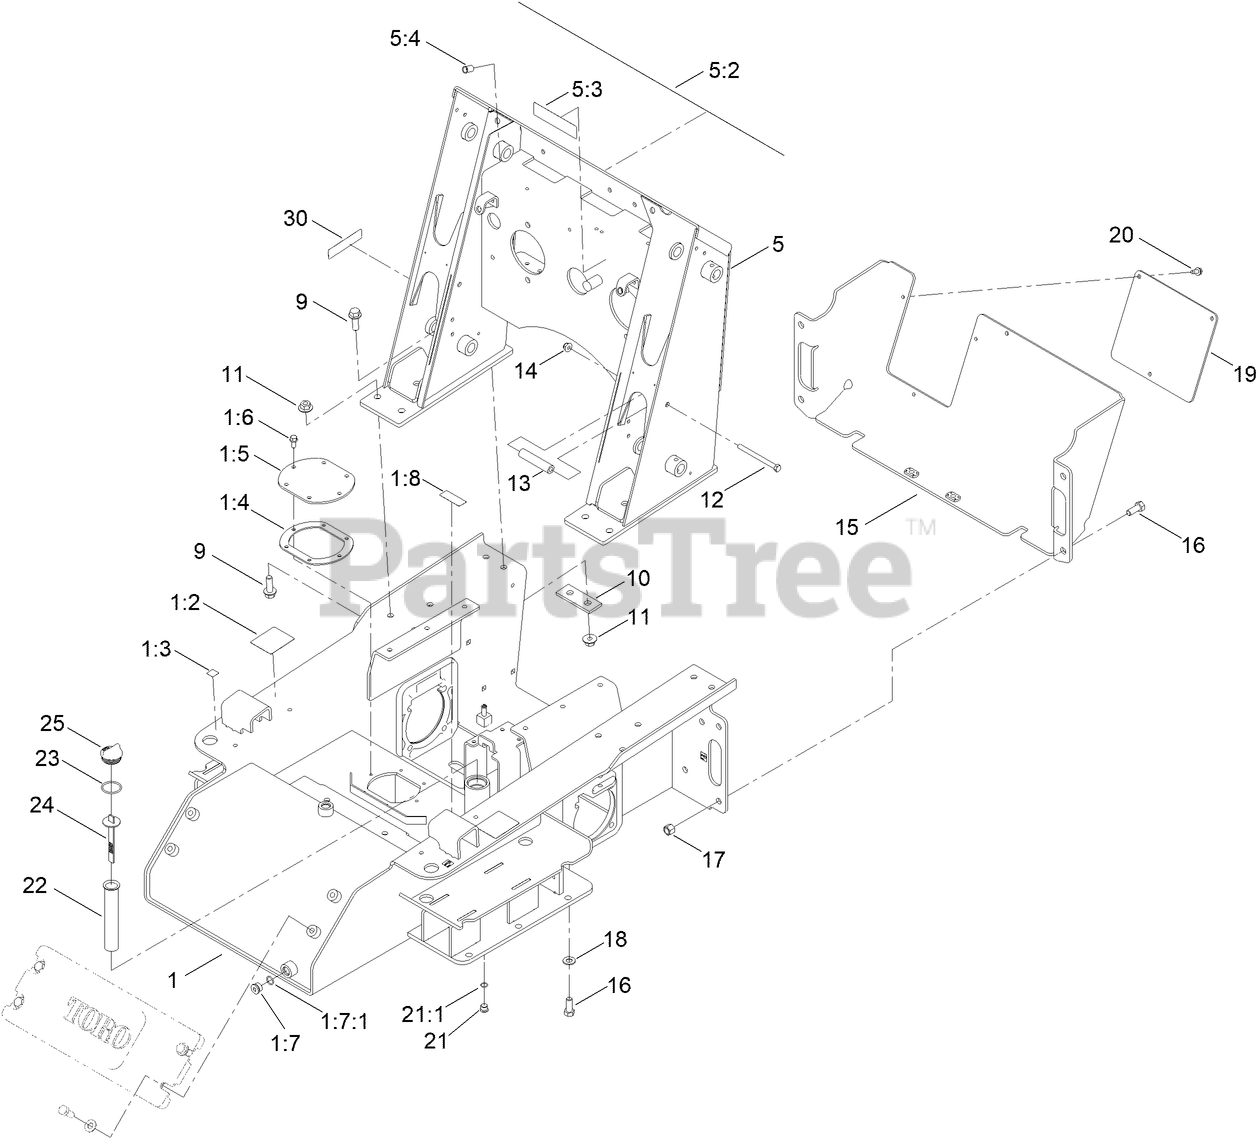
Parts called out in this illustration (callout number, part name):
1	CHASSIS ASM
1:2	DECAL-WARNING
1:3	DECAL-POINT, LIFT
1:4	GASKET-COVER, ACCESS
1:5	COVER-TANK
1:6	SCREW-HHF
1:7	PLUG-HEX
1:7:1	O-RING
1:8	DECAL-OIL, HYD
5	LOADER TOWER ASM
5:2	DECAL-PANEL, CONTROL
5:3	DECAL-DANGER
5:4	NUT-CLINCH
9	SCREW-HHF
10	PLATE-STIFFENER
11	NUT-LOCK, FLANGE
12	SCREW-HH
13	TUBE-SPACER
14	NUT-HF, NI
15	COVER-REAR
16	SCREW-HH
17	NUT-LOCK, NI
18	WASHER-FLAT
19	PANEL-REAR
20	SCREW-THD ROLL, HWH
21	PLUG-HEX, HOLLOW
21:1	O-RING
22	FILTER-SCREEN
23	O-RING
24	DIPSTICK-OIL
25	PLUG-PLASTIC
30	DECAL-ARRESTOR, SPARK
